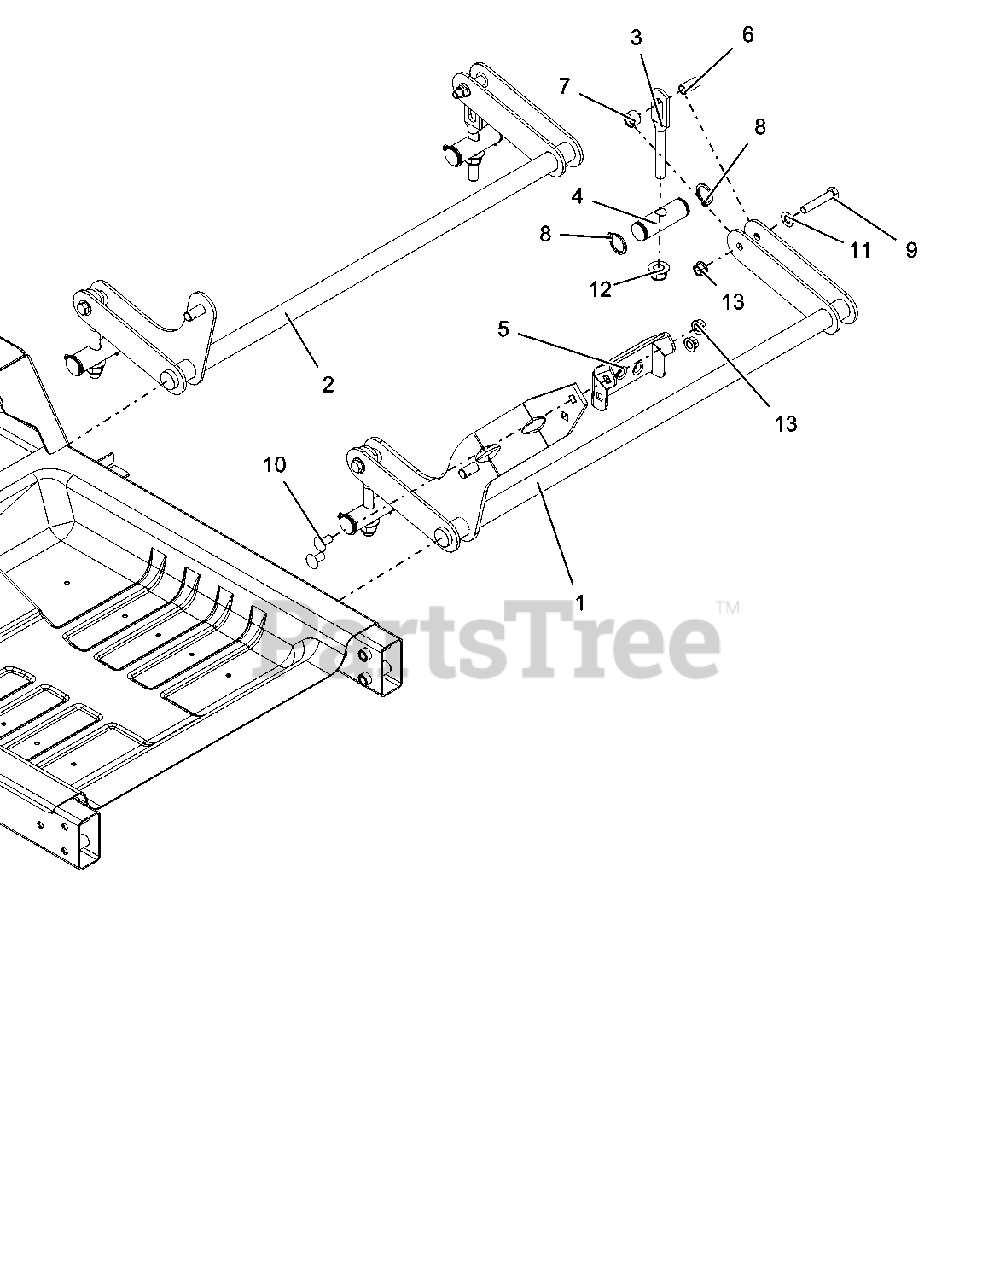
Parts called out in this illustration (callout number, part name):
1	WLDMT, FRONT DECK PIVOT
2	WLDMT, REAR DECK PIVOT
3	LINK, DECK
4	SHAFT, DECK LINK PIVOT
5	PEDAL, DECK LIFT (BOLT ON)
6	BSHG-SLV .385X.500X1.045
7	BSHG-SLV .510X.751X.475
8	RG-RTNG-EXT 1.00X.078
9	BLT-HEX .38-16X2.00 GR8 YWZC
10	BLT,RHSN .38-16X.75 G5 BFP
11	@WSHR-FL-STL.406X.812X.065 YWZ
12	@NUT-LK-NYL-FLG .50-13 YWZC
13	NUT-LK-CTR-FLG .38-16 YWZC
